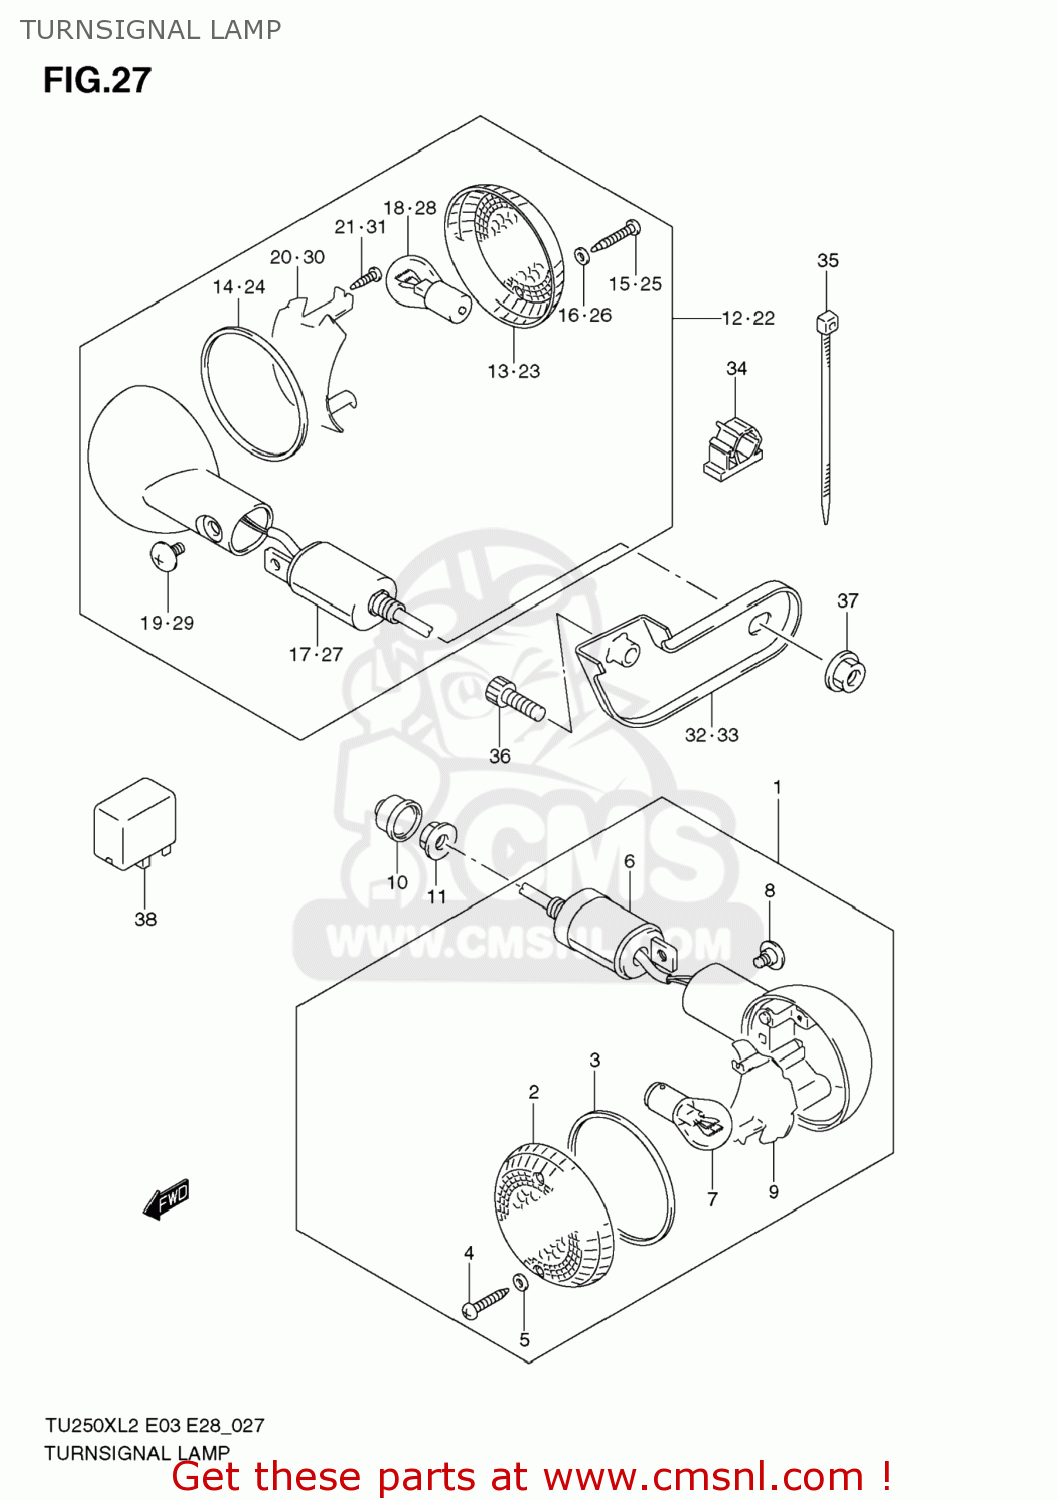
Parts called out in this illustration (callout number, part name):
1	LAMP ASSY,FR TURN SIGNAL
2	LENS
3	GASKET (NAS)
4	SCREW
5	GASKET (NAS)
6	STAY,TURNSIGNAL FR
7	BULB(12V21W)
8	SCREW
9	REFLECTOR
10	COVER,TURNSIGNAL
11	NUT
12	LAMP ASSY,RR TURNSIGNAL,R
13	LENS
14	GASKET (NAS)
15	SCREW
16	GASKET (NAS)
17	STAY,TURNSIGNAL FR
18	BULB(12V21W)
19	SCREW
20	REFLECTOR
21	SCREW
22	LAMP ASSY,RR TURNSIGNAL,L
23	LENS
24	GASKET (NAS)
25	SCREW
26	GASKET (NAS)
27	STAY,TURNSIGNAL FR
28	BULB(12V21W)
29	SCREW
30	REFLECTOR
31	SCREW
32	BRACKET,RR TURNSIGNAL,R
33	BRACKET,RR TURNSIGNAL,L
34	CLAMP
35	CLAMP(L:145)
36	BOLT
37	NUT
38	RELAY ASSY,TURNSIGNAL LAMP
